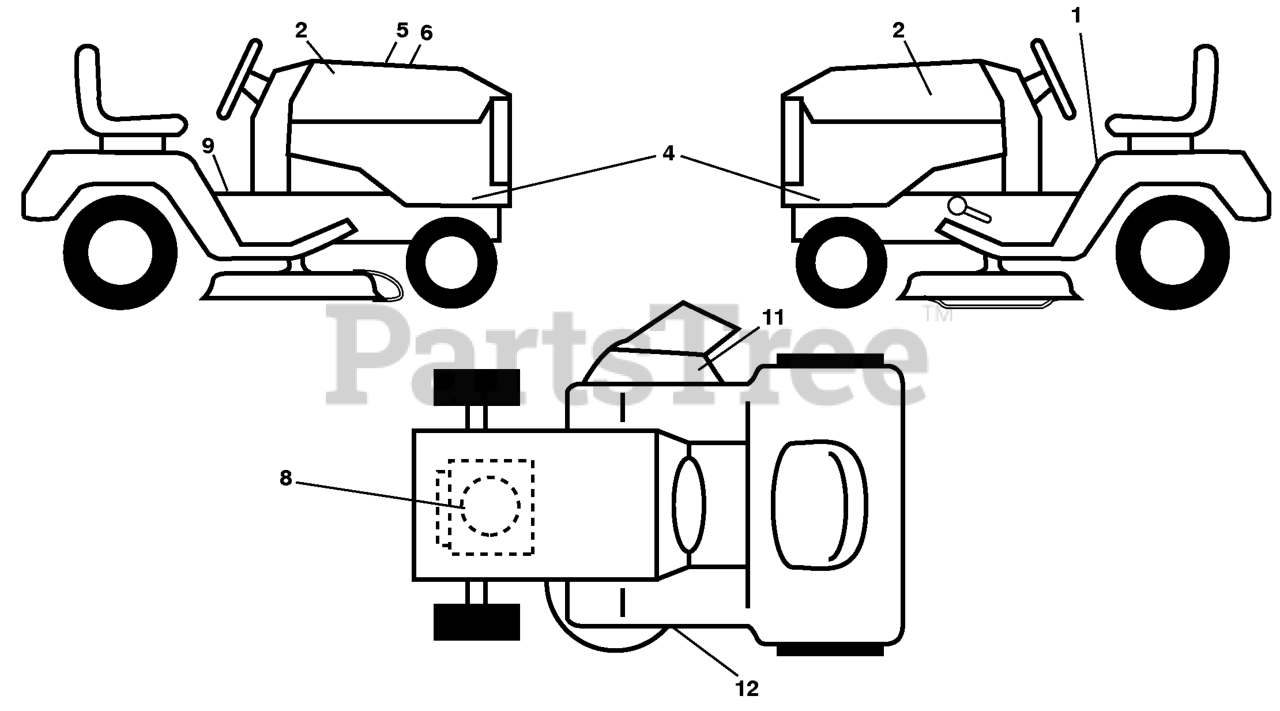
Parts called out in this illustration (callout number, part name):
1	DECAL.FENDER.WARNING.ENG
2	RP.DECAL.BADGE.170MM.TEXTLOGO
4	DECAL.SDPNL.LTH18538.B&S.HUS
5	DECAL.WARNING.CUST.RESP.E85.
6	DECAL, REPLACEMENT
8	DECAL, ENGINE HP
9	DECAL BTRY SYMBOLS
11	DECAL.WARN.KEEP.HAND.AWAY
12	DECAL.V-BELT.SCHEMATIC.36/38/9
